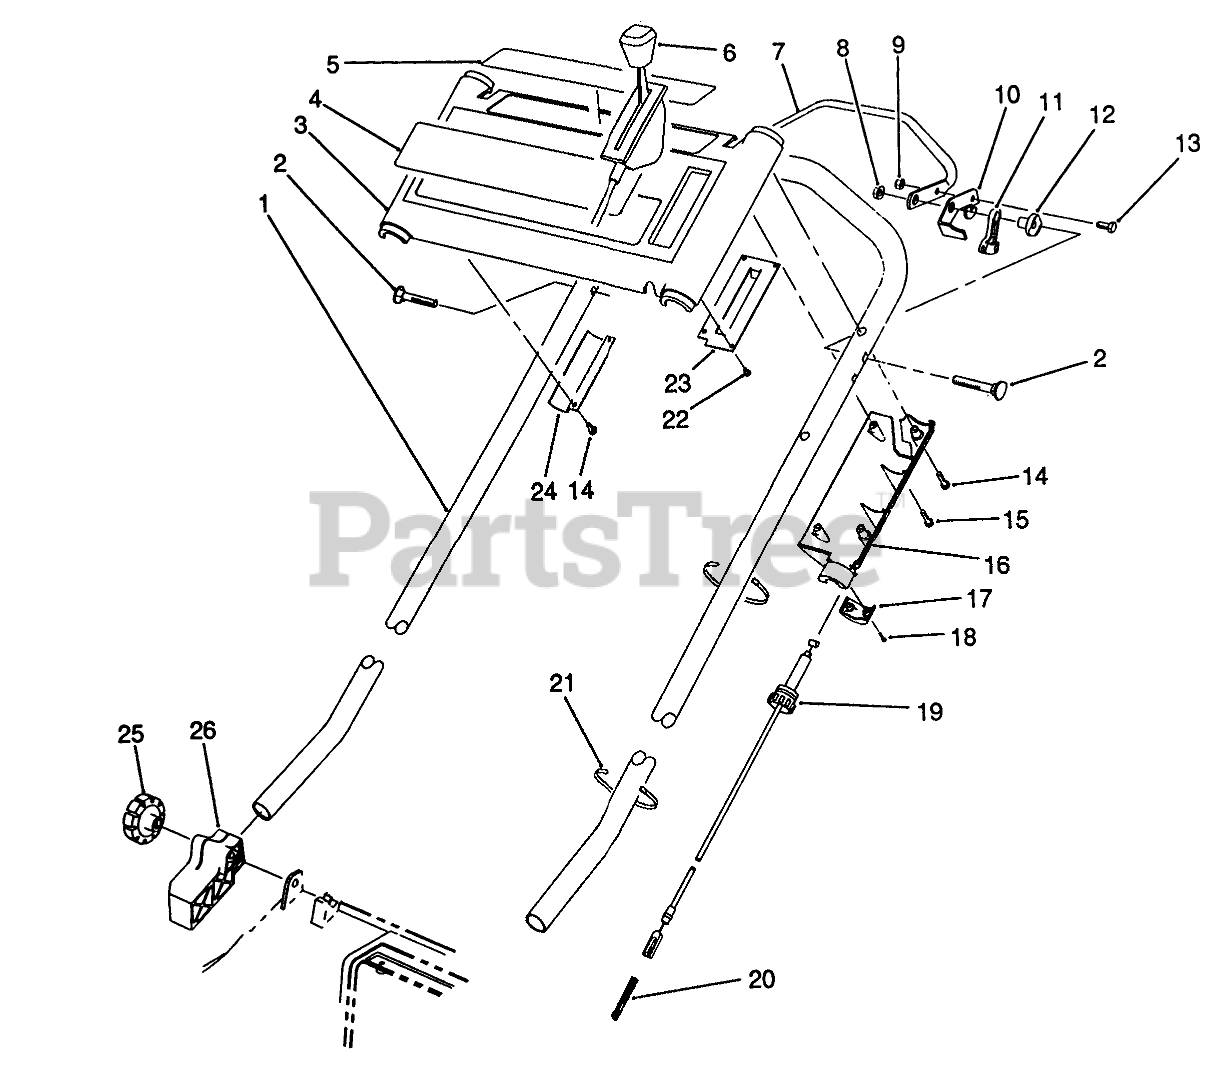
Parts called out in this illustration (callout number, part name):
1	Handle
2	SCREW-HANDLE
3	Panel-Control (Incl. Ref #4, & 5)
4	DECAL - TORO
5	DECAL - PANEL DANGER
6	THROTTLE CONTROL
7	CONTROL BAR
8	NUT-LOCK, NI
9	NUT-LOCK, NI
10	CONTROL LEVER
11	LEVER-TRACTION
12	SPACER-SUPPORT
13	SCREW-HH
14	SCREW-PPH, PLASTITE
15	Screw
16	Cover-Throttle Lower
17	LOWER THROTTLE CAP
18	#4-14X.62 PLASTITE SCW
19	TRACTION CABLE
20	SPRING-COMPRESSION
21	TIE-CABLE
22	#6-19X.25 PLASK FORM SC
23	THROTTLE PLATE
24	Bracket-Panel
26	MOUNT-HANDLE, RH
